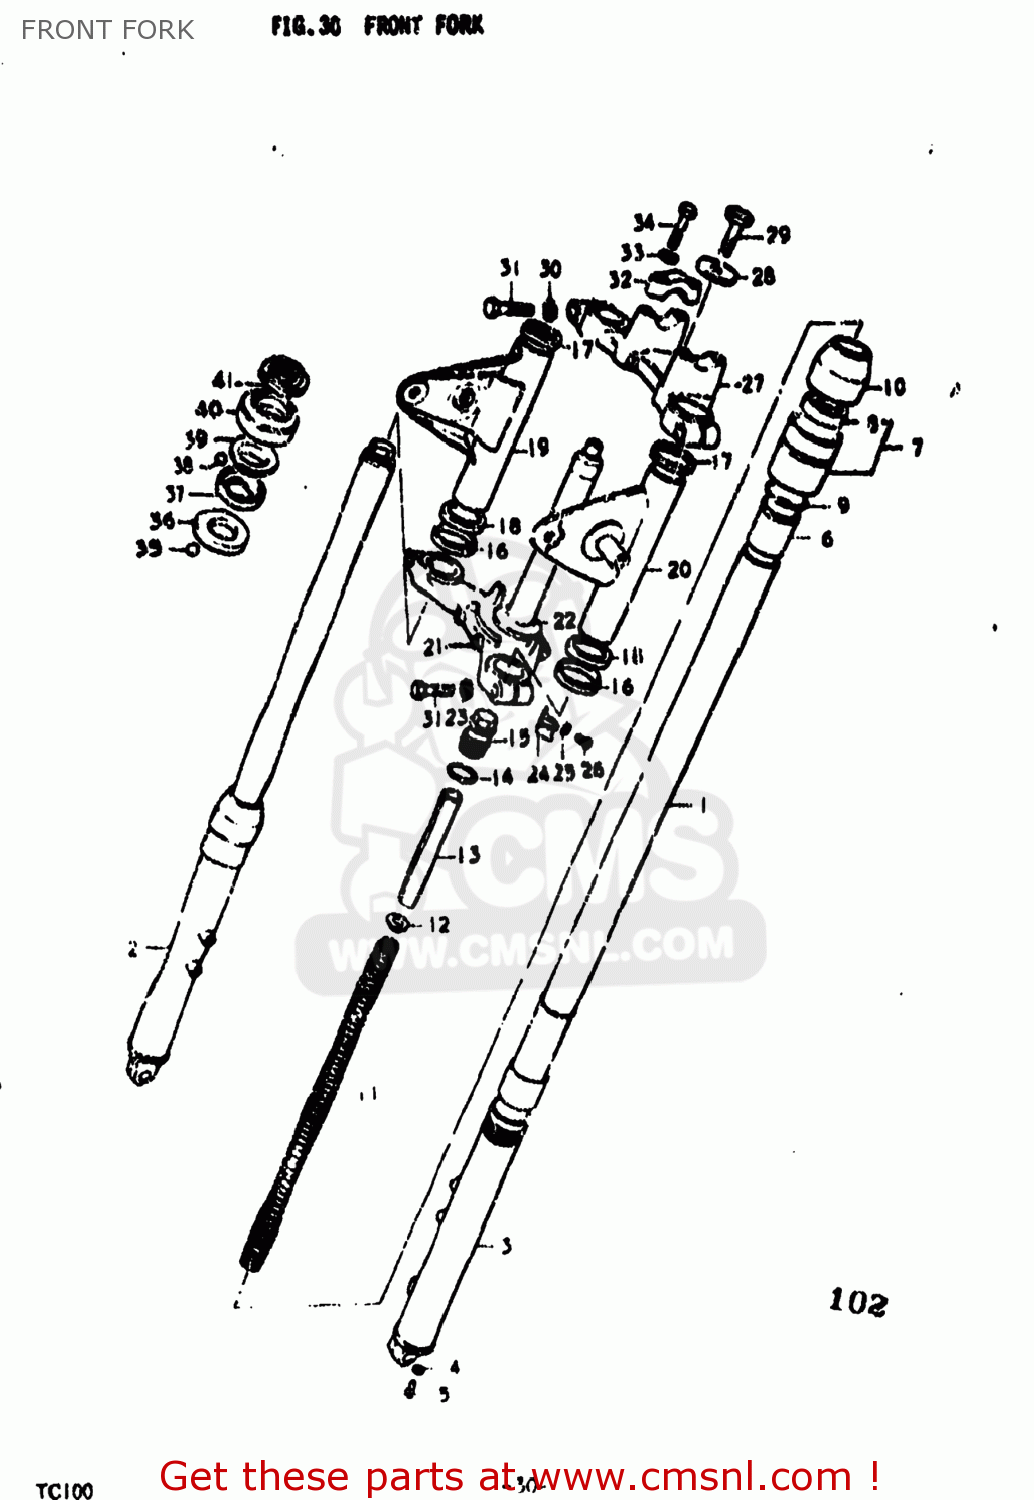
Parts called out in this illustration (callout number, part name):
1	TUBE,INNER
2	TUBE,OUTER,LEFT
3	SEAL,OIL
4	RING,SNAP
5	WASHER,FRONT FORK
6	STUD BOLT
7	GASKET,DRAIN,PLUG (NAS)
8	SCREW
9	SNAP RING
10	PISTON
11	CYLINDER,FRONT FORK
12	PIECE,OIL LOCK
13	SEAL,DUST
14	O-RING,FORK INNER TUBE
15	STEM,STEERING
16	RACE,STEERING OUTER LWR
17	SPRING
18	GUIDE,SPRING
19	SPACER,SPRING
20	BRACKET,HEADLAMP HOUSING
21	BRACKET,HEADLAMP,LEFT
22	BRACKET,HEADLAMP HOUSING
23	BRACKET,HEADLAMP,LEFT
24	GASKET
25	SEAT,HEADLAMP BRACKET
26	GUIDE, COVER
27	CUSHION,HEADLAMP BRACKET
29	HEAD,STEERING STEM
30	HOLDER,HANDLEBAR
31	BOLT,FR FORK
32	CLIP
33	SCREW
34	LOCK WASHER
35	BOLT,FORK INNER TUBE
36	BOLT
37	Bolt
38	LOCK WASHER
39	WASHER,STEM HEAD(10.5X30X3.2)
40	CUSHION,HEAD LAMP BRACKET
41	NUT (8MM)
42	BOLT,FORK INNER TUBE F
43	LOCK WASHER
44	CLIP
45	BOLT,FR FORK LWR(12X33)
46	WASHER,LOCK 12
47	HOLDER,AXLE
48	LOCK WASHER
